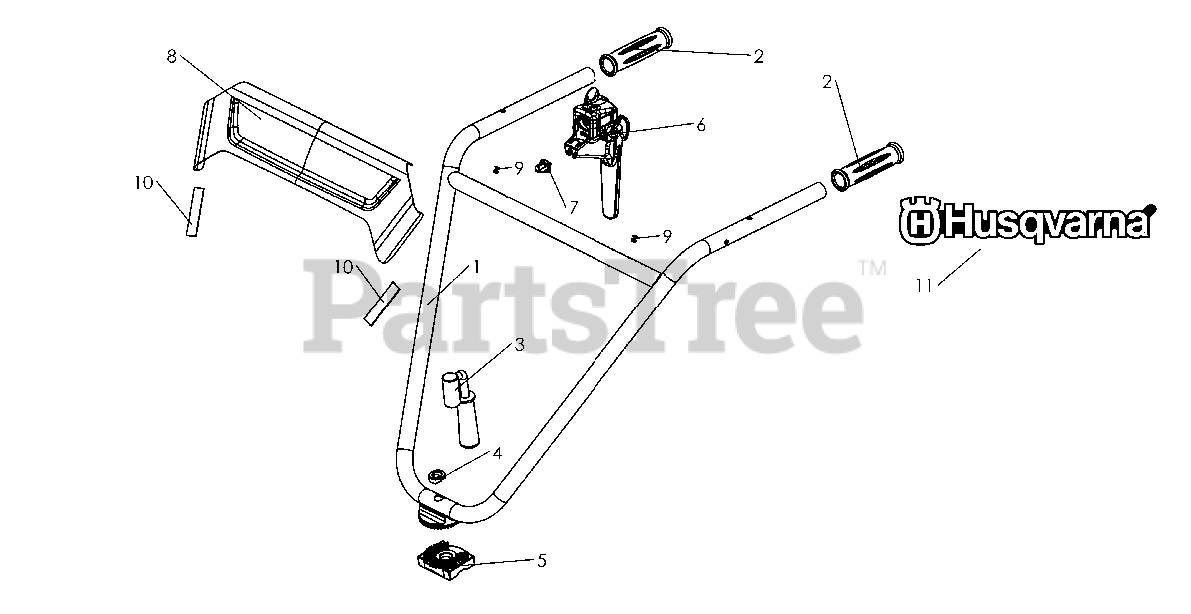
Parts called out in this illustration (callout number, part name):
2	HANDLE
4	SPACER
5	SPACER
